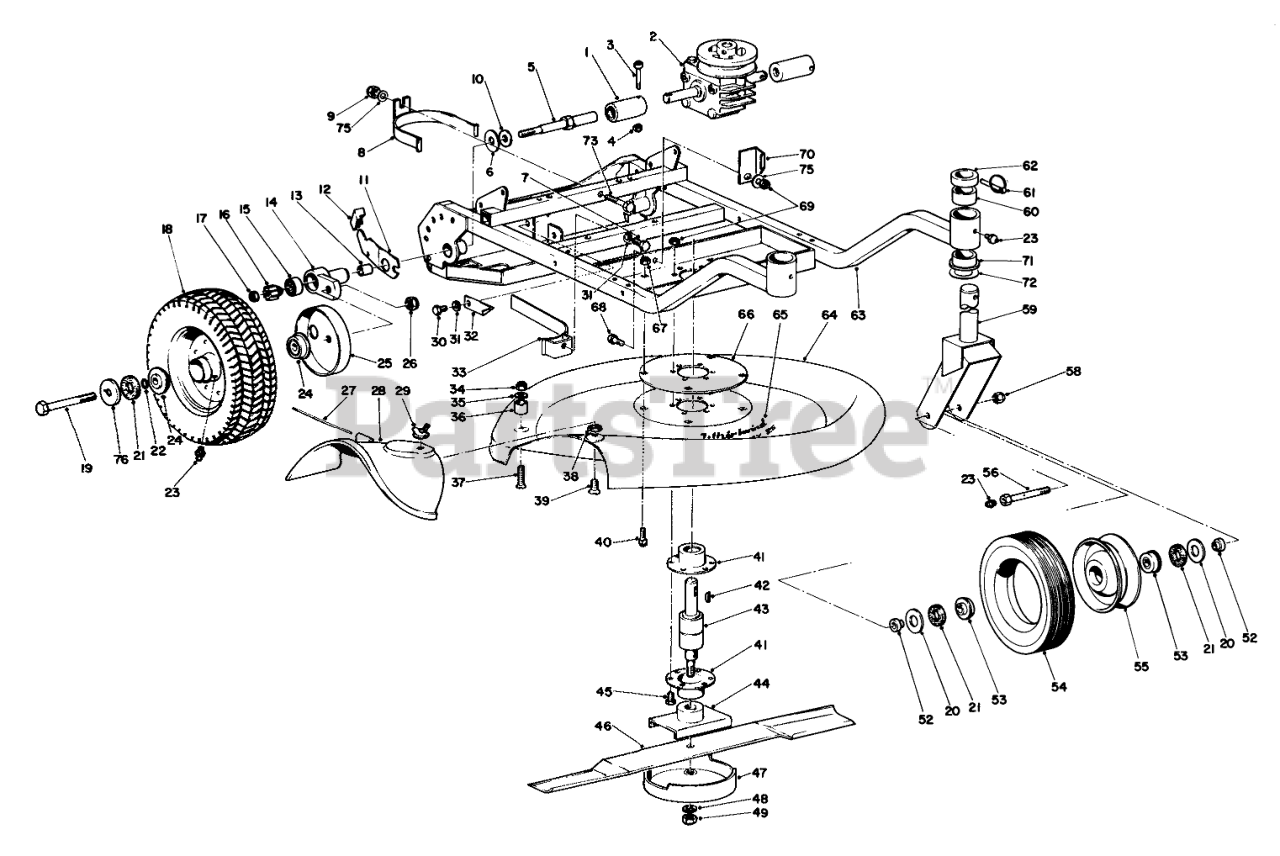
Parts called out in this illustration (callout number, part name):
1	CLUTCH ASM
2	Transmission Assembly
3	DRIVE SCREW
4	NUT-LOCK, NI
5	DRIVE SPINDLE
6	Washer
7	SCREW-HH
8	Belt Retainer W.A.
9	Locknut
10	Washer
11	RH SPRING ARM ASM
13	BUSHING
14	Pivot Arm Assy., Right (Incl. Ref. # 13 & 15)
15	.375 RPP BALL BEARING
16	Pinion Kit
17	NUT-HJ
18	REAR WHEEL & TIRE ASM
19	SCREW-HH
20	WASHER-FLAT
21	Washer
22	O-RING
23	FITTING-GREASE
24	BEARING
25	Wheel Cover
26	NUT-LOCK, NI
27	Hinge Pin
28	Deflector
29	Wing Nut
30	SCREW-HH
31	Lockwasher
32	Belt Retainer
33	Belt Retainer W.A.
34	NUT-KEPS
35	WASHER-FLAT
36	Spacer
37	Screw
38	PAL NUT
39	5/16-18X7/8 FLT HD MS
40	BOLT-CARR
41	BEARING HOUSING
42	KEY-WOODRUFF
43	Bearing Spindle
44	Retainer
45	SCREW-HH
46	25 HD BLADE
48	WASHER-LOCK
49	NUT-HEX
52	CASTOR SPACER
53	BEARING-BALL
54	1.75-8 SEMIPNEU TIRE
55	Wheel (Incl. Ref. #53 & 54)
56	AXLE BOLT
58	NUT-HEX
59	CASTOR FORK WA RO
60	7/8 ID X 1.128 X 7/8 LG BSHG
61	PIN-LYNCH
62	HT OF CUT SPACER
63	Frame (Incl. Ref. #60 & 71)
64	Housing
65	Decal
66	Plate
67	NUT-HEX
68	SCREW-HH
69	Nut
70	Belt Retainer
71	FLANGE BUSHING
72	WASHER
73	SCREW-HH
75	WASHER-PLAIN
76	SLINGER
